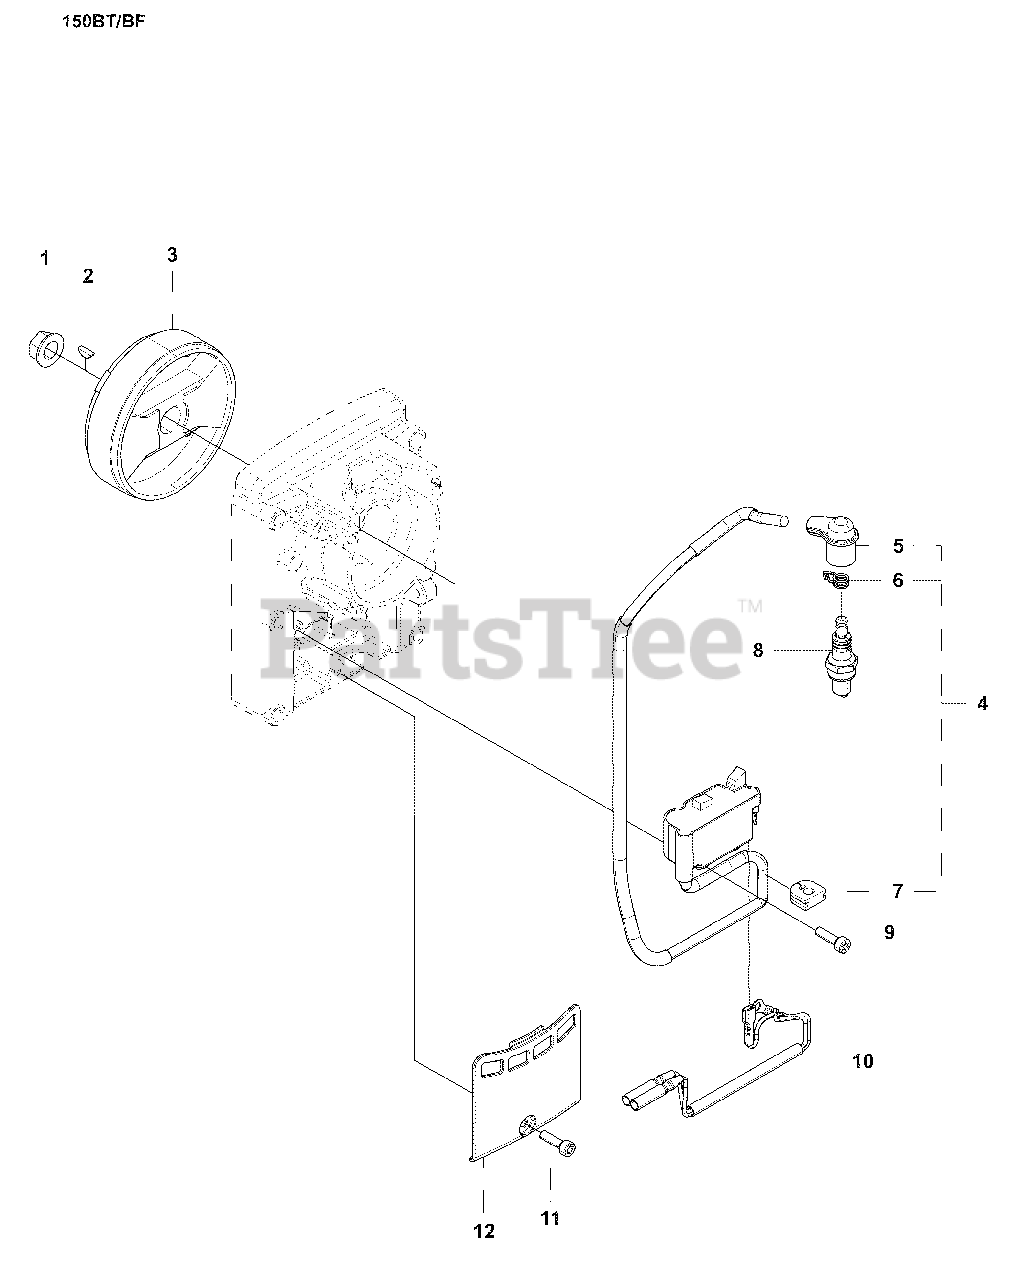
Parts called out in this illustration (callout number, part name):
1	NUT
2	KEY
3	FLYWHEEL
4	IGNITION COIL
5	CAP
6	SPRING
8	SPARKPLUG NGK CMR7H
9	BOLT
10	CORD-C
11	BOLT
